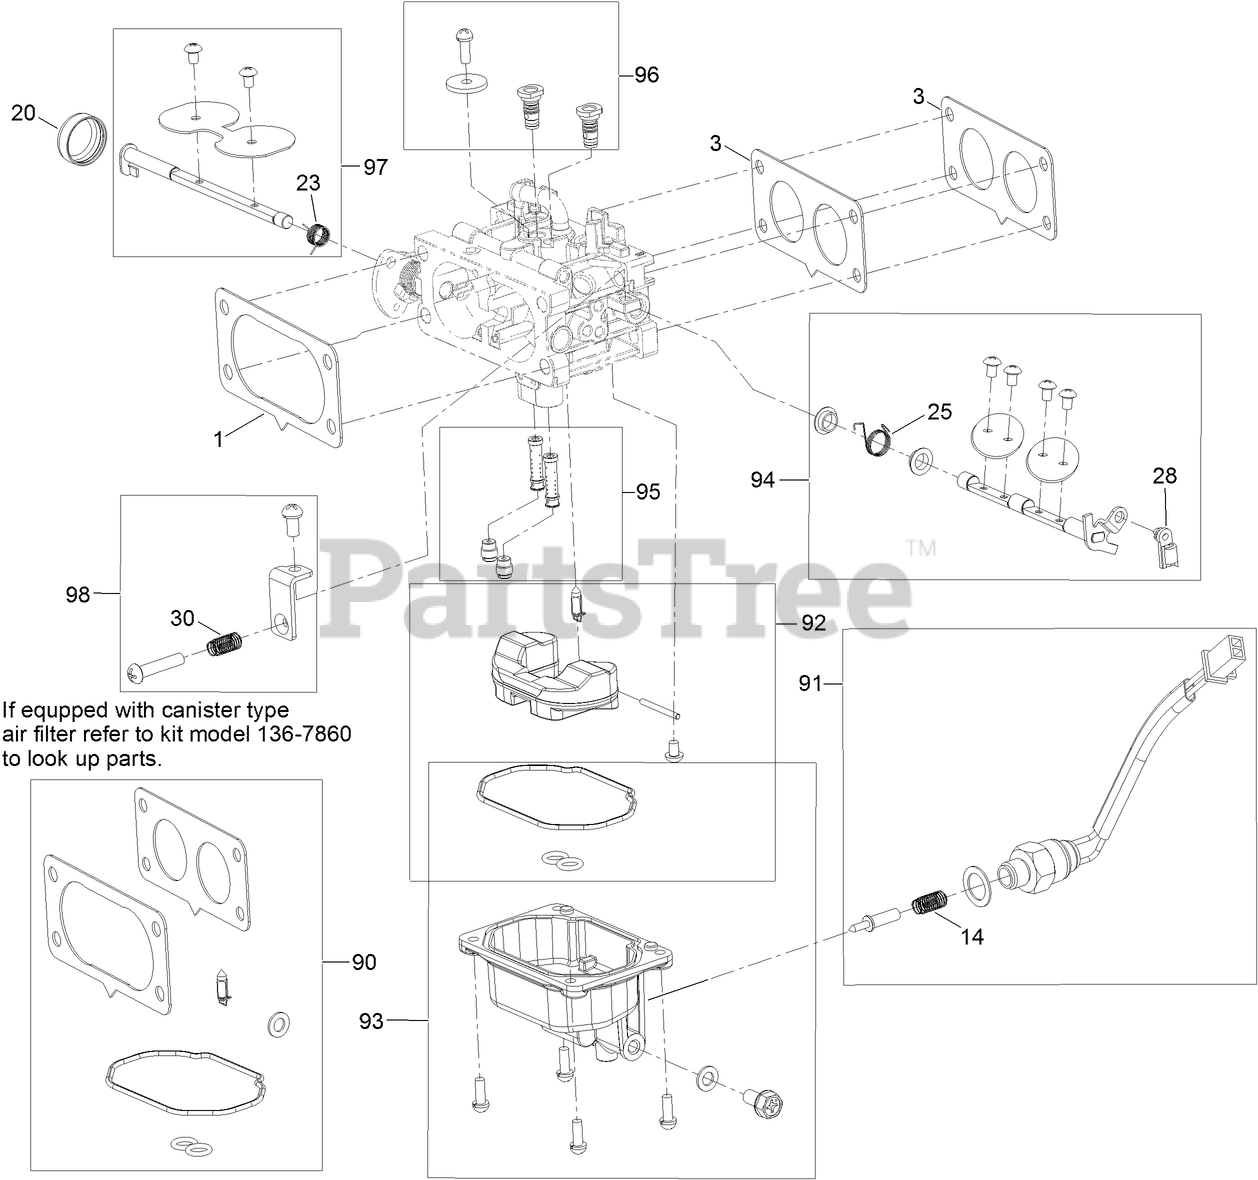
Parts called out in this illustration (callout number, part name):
1	CARBURETOR
1	GASKET-CARBURETOR
3	GASKET-CARBURETOR
14	SPRING
20	COVER-SHAFT, CHOKE
23	SPRING
25	SPRING
28	CLAMP-LOCK
30	SPRING
90	CARBURETOR REPAIR KIT
91	SOLENOID KIT
92	FLOAT KIT
93	BOWL KIT
94	THROTTLE SHAFT KIT
95	NOZZLE AND JET KIT
96	AIR JET KIT
97	CHOKE SHAFT KIT
98	IDLESTOP KIT
